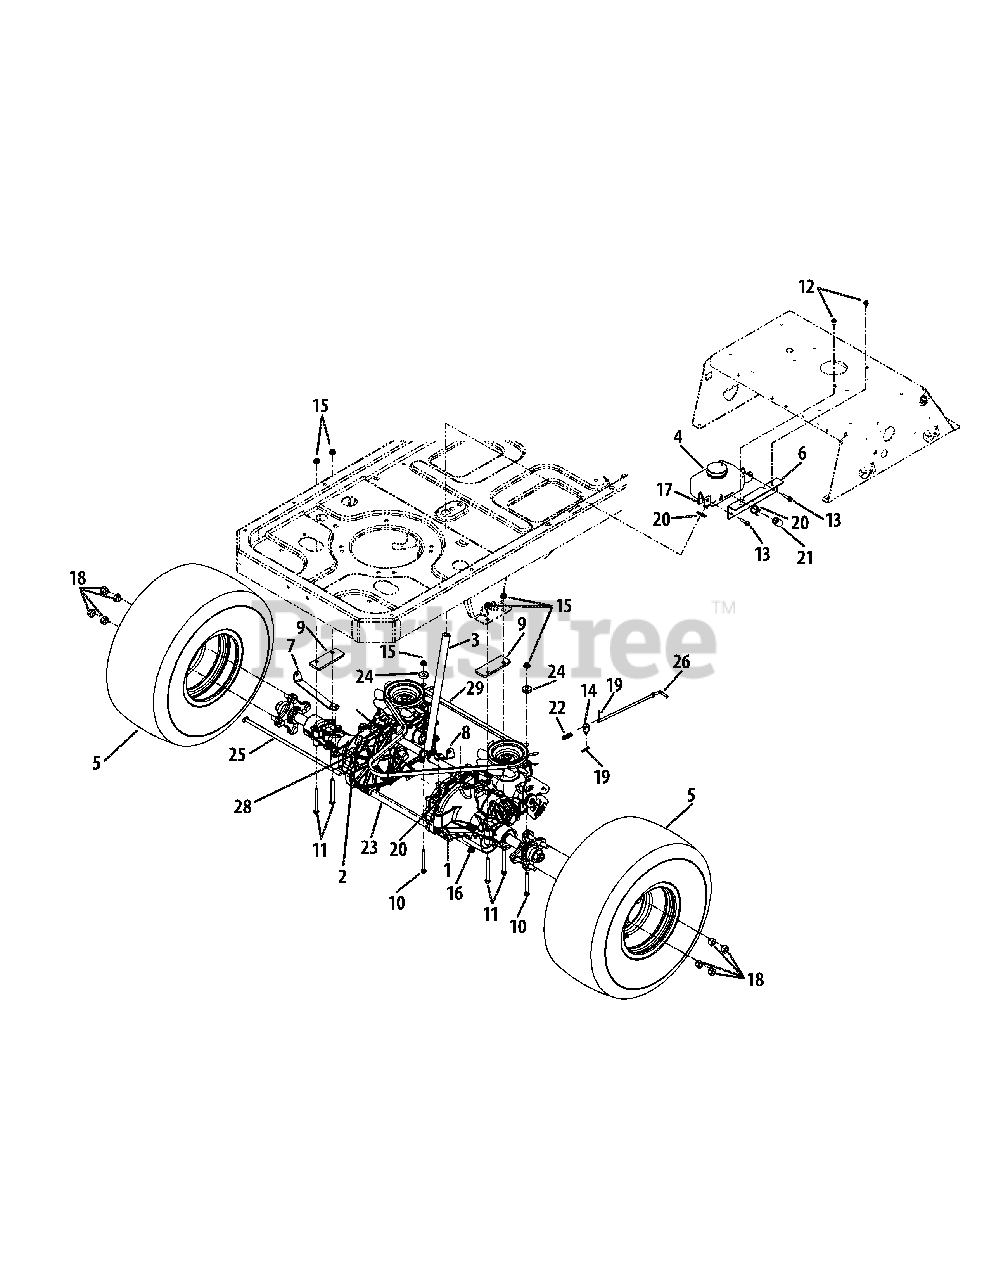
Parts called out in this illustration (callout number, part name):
1	Transmission Assembly (RH)
2	Transmission Assembly (LH)
3	Breather
4	Expansion Tank Assembly
5	Wheel Assembly, 20 x 10 x 8
6	Expansion Tank Bracket
7	Transmission Brace (LH)
8	Transmission Brace (RH)
9	Transmission Spacer
10	Hex Screw, 5/16-18 x 2.75
11	Hex Screw, 5/16-18 x 3.00
12	Screw, 1/4-20 x .500
13	Screw, 1/4-20 x 1.000
14	Ferrule, .325 x .312
15	Flangelock Nut, 5/16-18
16	Flangelock Nut, 3/8-16
17	Speed Nut, 1/4-20
18	Lug Nut, 7/16-14
19	Cotter Pin, .072 x 1.13
20	Hose Clamp, .750
21	Cap, 1/2 x .870
22	Compression Spring, .405 x 1.17
23	Extension Spring, .545 x 4.555
24	Flat Washer, .35 x 1.0 x .2
25	Rod, .337 x 14.75
26	Bypass Rod
27	Tube, 7/16 x 3/4 x 11.3
28	Straight Fitting, 9/16 x 1/2
29	V-Type Belt, 57.7
